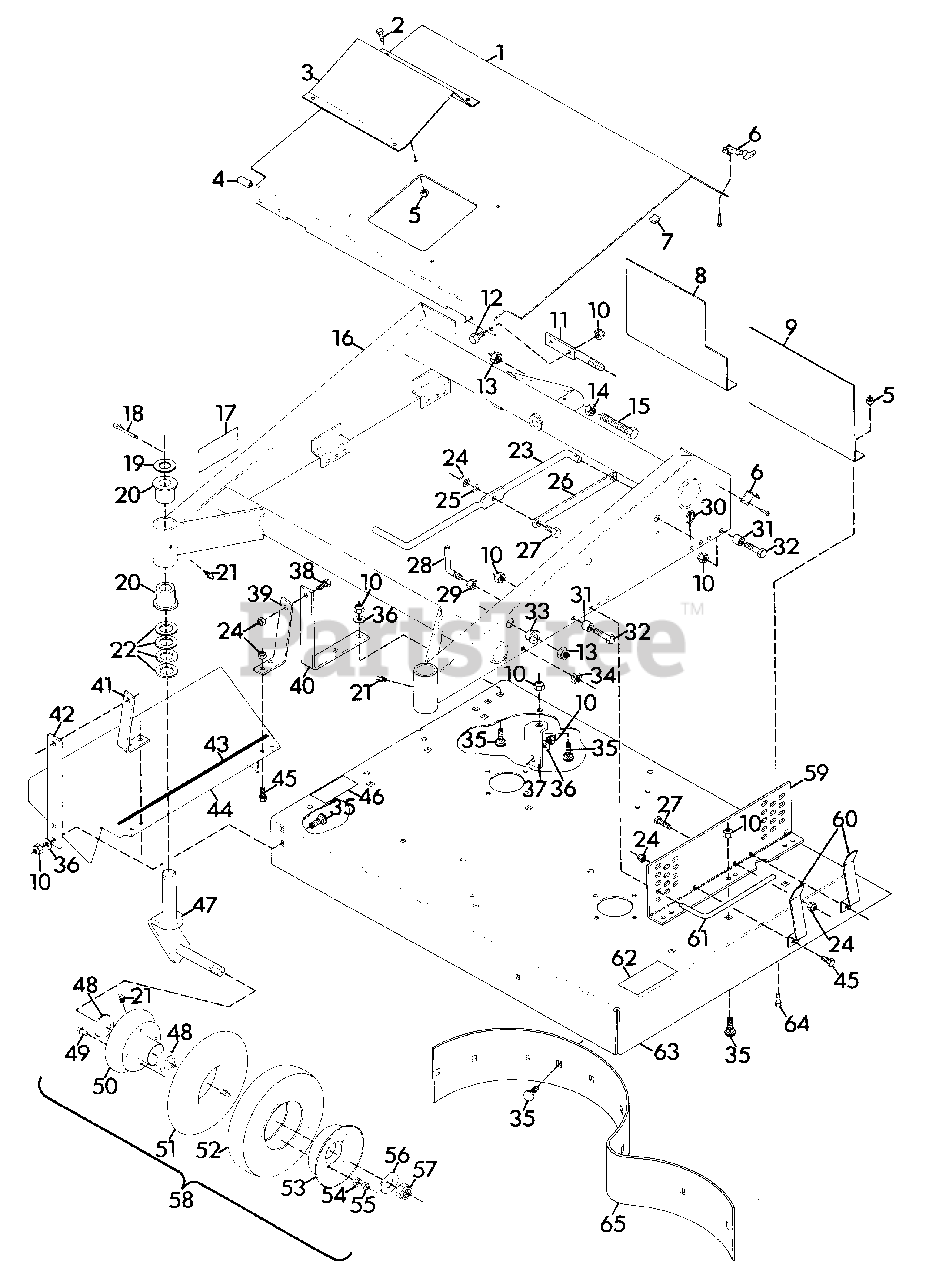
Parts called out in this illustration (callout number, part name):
1	SHIELD
2	BOLT, HEX 1/4-20X.625
3	COVER, HOLE
4	STRIP, BUMPER
5	NUT, LOCK 1/4-20
6	LATCH, FLEXIBLE DRAW
7	STOP
8	SHIELD, REAR R.H.
9	SHIELD, REAR L.H.
10	NUT, LOCK 3/8-16
11	BRACKET, HINGE
12	BOLT, HEX 3/8-16X.875
13	NUT, LOCK 1/2-13
14	NUT, JAM 1/2-13 HEX
15	BOLT, HEX 1/2-13X3.00 ALL THD.
16	WELDMENT, MOWER FRAME
17	DECAL, DANGER HAND
18	PIN, COTTER .187X1.50
19	RACE, BEARING THRUST
20	BUSHING, PIVOT
21	FITTING, LUBE 1/4-28
22	WASHER, FLAT 1.0X1.5X.125
23	HANDLE, LIFT
24	NUT, LOCK 5/16-18
25	WASHER, FLAT .344X.688X.065
26	STRAP, LIFT
27	BOLT, HEX 5/16-18X1.00
28	HANDLE, ADJUSTING
29	NUT, HEX 3/8-16
30	PIN, KLIK
31	BUSHING .391X.622X.670
32	BOLT, HEX 3/8-16X1.50
33	BUSHING, .513X.750X.625
34	NUT, LOCK 3/8-16
35	BOLT, 3/8-16X1.00 RD HD SQ NK
36	WASHER, FLAT .406X.812X.065
37	BRACKET
38	BOLT, HEX 5/16-18X1.25
39	BRACKET, CHUTE REAR
40	BRACKET
41	BRACKET, CHUTE FRONT
42	BRACKET
43	STRIPE
44	CHUTE, DISCHARGE
45	BOLT, HEX 5/16-18X.75
46	DECAL, WARNING EYE
47	WELDMENT, CASTER FORK
48	BEARING, GAUGE WHEEL
49	BOLT, HEX 3/8-24X.75
50	WHEEL, HALF WITH TUBE
51	TUBE, INNER
52	TIRE, GAUGE WHEEL
53	WHEEL, HALF PLAIN
54	WASHER, LOCK 3/8 SP HEAVY
55	NUT, HEX 3/8-24
56	WASHER, FLAT .812X1.496X.134
57	NUT, LOCK 3/4-10
58	WHEEL, GAUGE
59	BRACKET, MOWER SUPPORT
60	SPRING, PIN
61	PIN, MOWER LOCKING
62	DECAL, DANGER FOOT
63	WELDMENT, 36" DECK
64	BOLT, HEX 1/4-20X.750
65	SCROLL
NS	BRACKET, MOWER SUPPORT
NS	DECAL, COMMERCIAL FRONT
NS	DECAL, GRAVELY LOGO
NS	DECAL, BELT DIAGRAM
